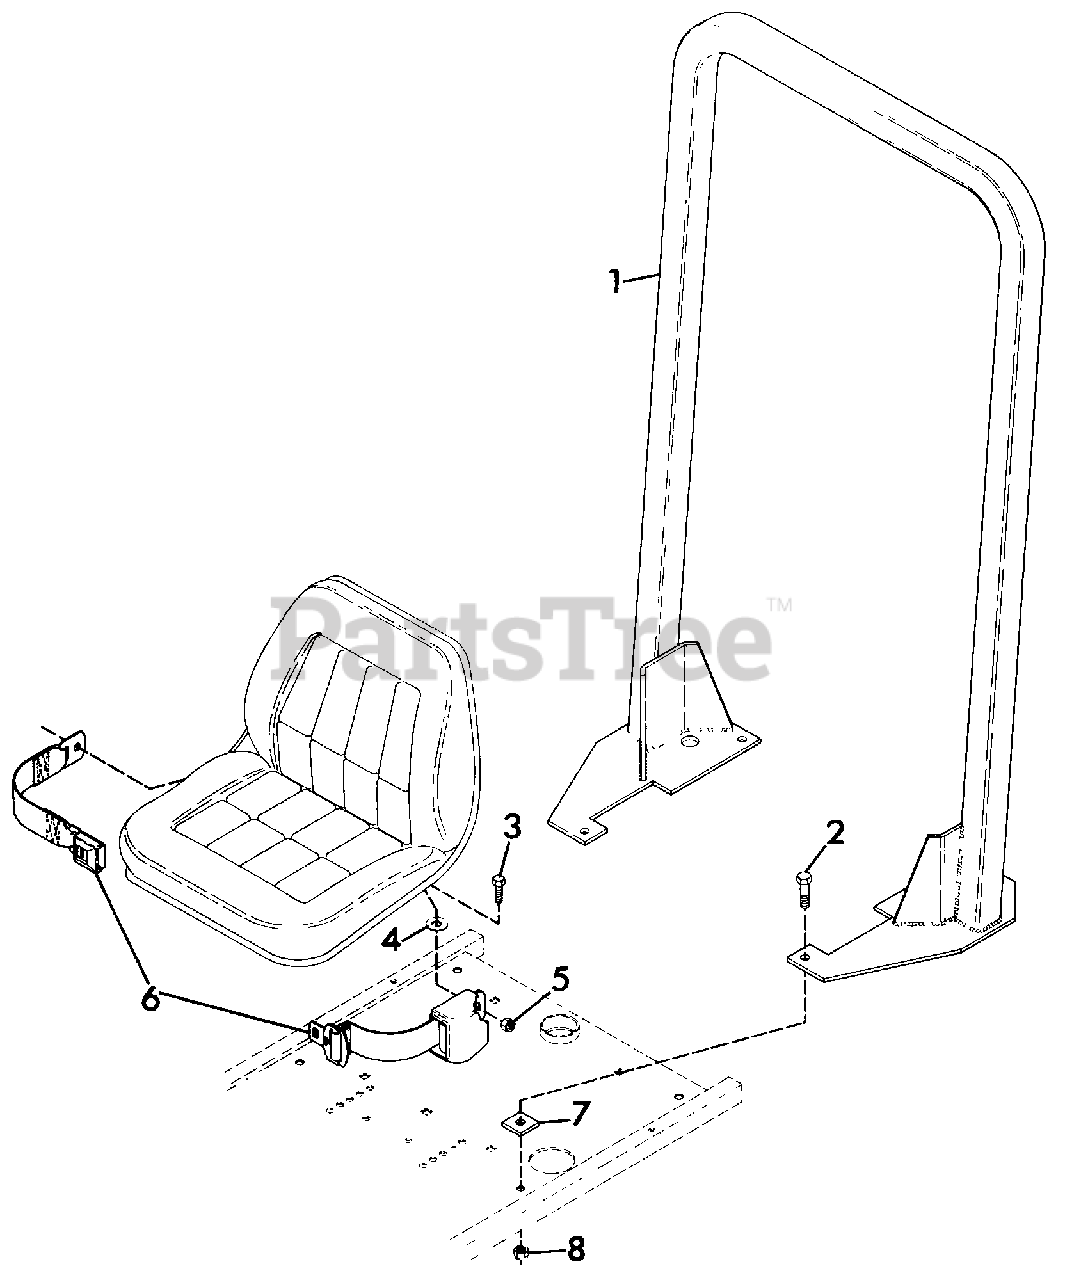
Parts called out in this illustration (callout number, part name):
1	WELDMENT, ROLL OVER BAR
2	BOLT, HEX 1/2-13X1.50
3	BOLT, HEX 7/16-14X1.00
4	WASHER, FLAT .531X1.062X.095
5	NUT, LOCK 7/16-14 HEX
6	ASSEMBLY, SEAT BELT
7	PLATE, SPACER
8	NUT, LOCK 1/2-13
